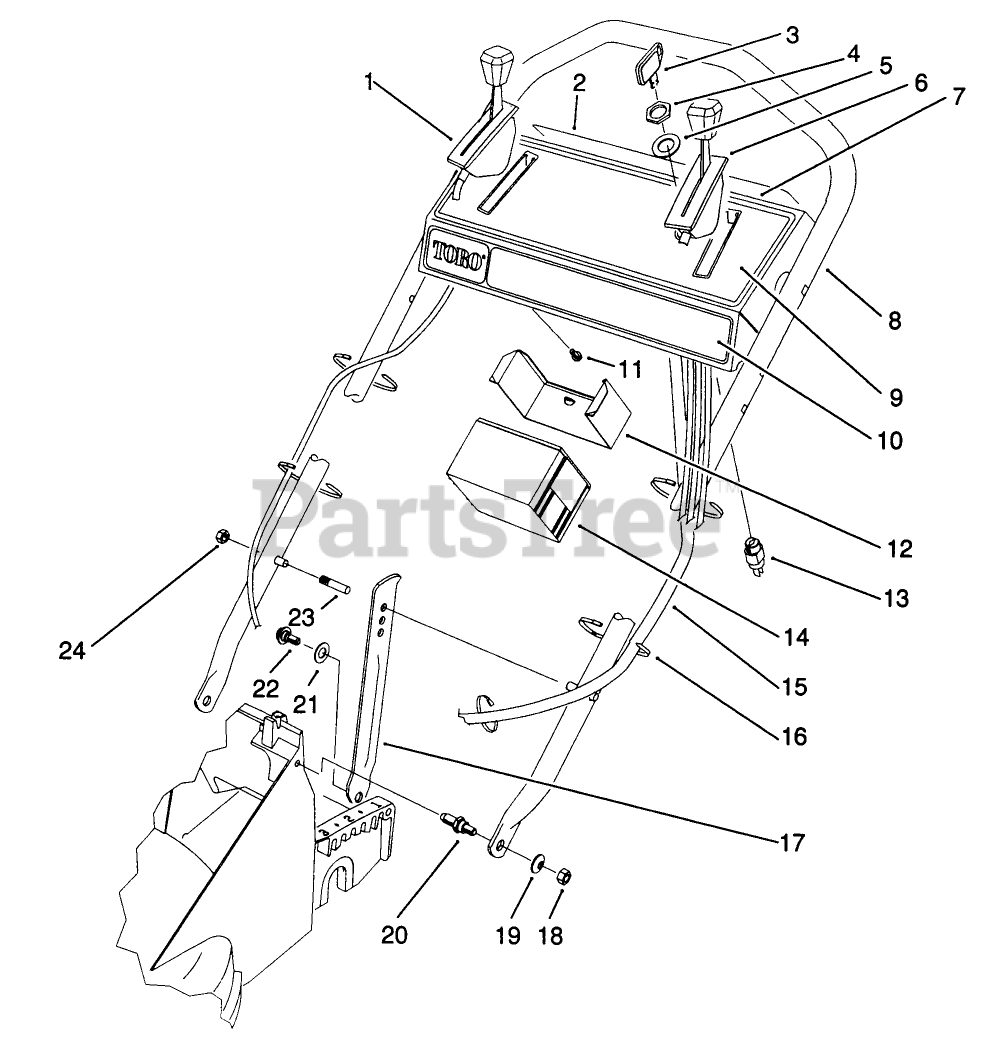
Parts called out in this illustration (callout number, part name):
2	DECAL-PANEL, DANGER
3	KEY-IGNITION
4	NUT-HH
5	WASHER-LOCK
6	THROTTLE CONTROL
7	PANEL W/ DECAL ASM
11	SCREW-HWHTF
13	STARTER SWITCH ASM
14	BATTERY ASSEMBLY,WET
16	TIE-CABLE
18	NUT-LOCK, NI
19	WASHER-PLAIN
22	SCREW-SHOULDER
23	HANDLE PIN
24	NUT-LOCK, NI
